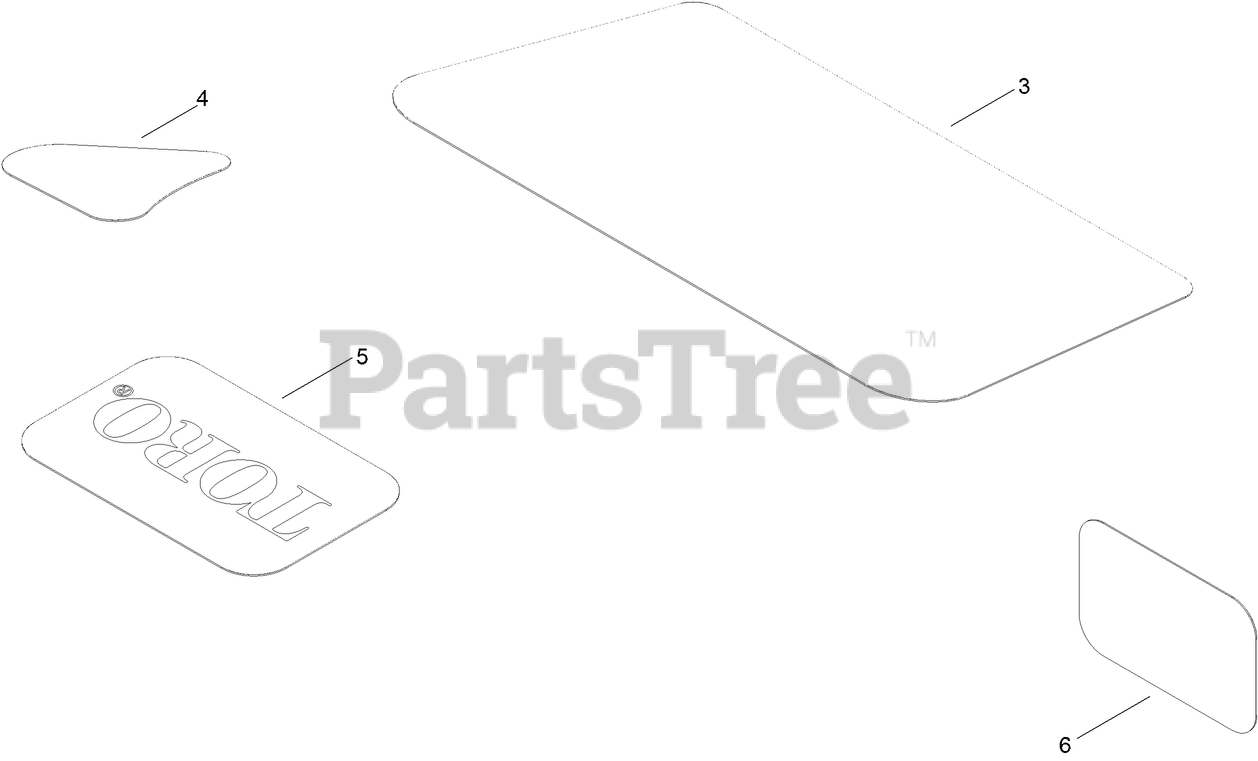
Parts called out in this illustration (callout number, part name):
3	DECAL-ENGINE
4	DECAL-DRAIN, OIL
6	PLACARD-INTAKE
